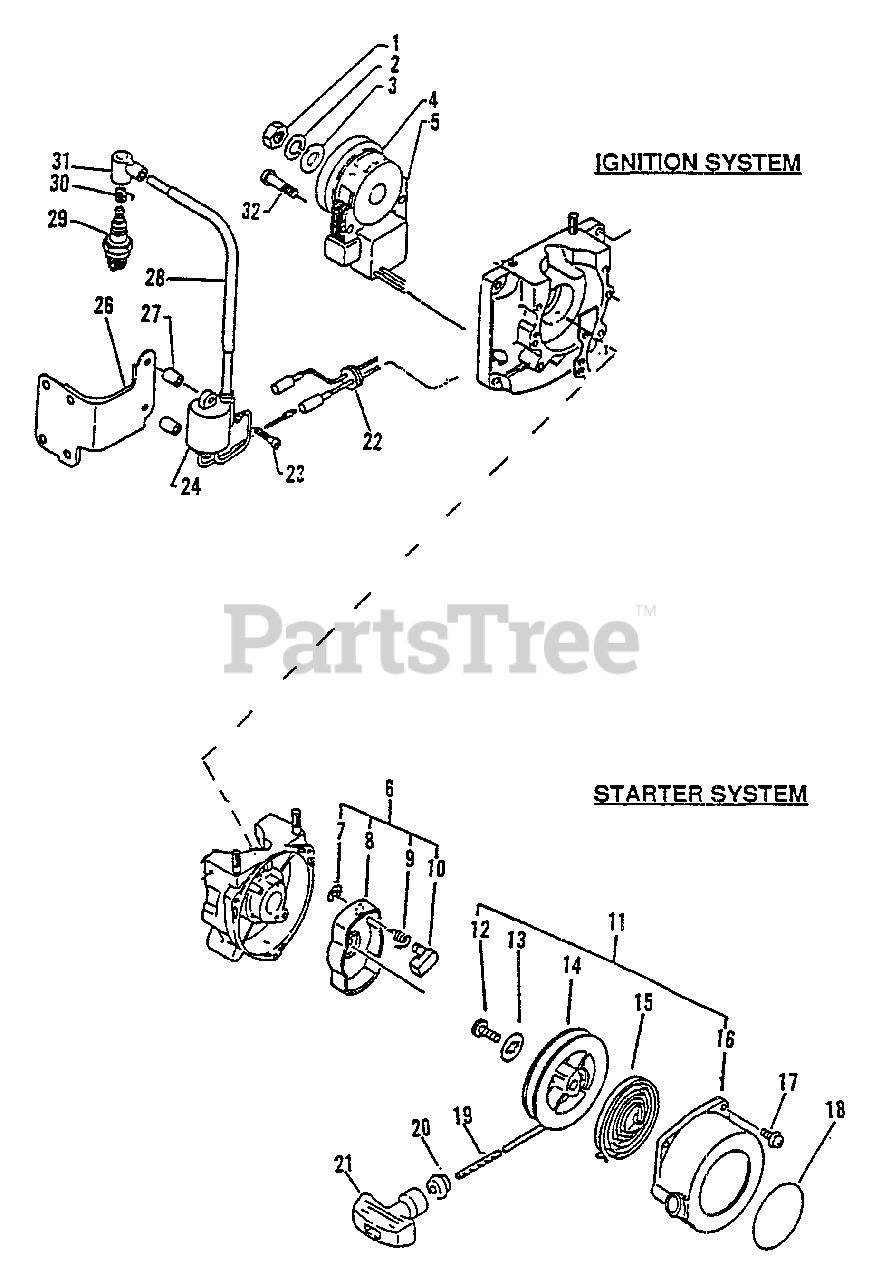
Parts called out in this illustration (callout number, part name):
2	LOCKWASHER
4	FLYWHEEL
5	COIL, IGNITION
6	STARTER PAWL ASSY
7	RING, RETAINING - 4
8	CATCHER, PAWL
9	SPRING, RETURN
10	PAWL, STARTER
11	STARTER ASSY
14	REEL, ROPE
15	SPRING, REWIND
16	CASE, STARTER
17	SCREW - 5X18
18	LABEL - LESCO
19	ROPE, STARTER - 4X880
20	GUIDE, ROPE
21	GRIP, STARTER
23	SCREW - 4X25
24	COIL, IGNITION
29	SPARK PLUG -- BM-6A
30	TERMINAL, SPARK PLUG CAP
31	CAP, SPARK PLUG
32	SCREW - 5X25
